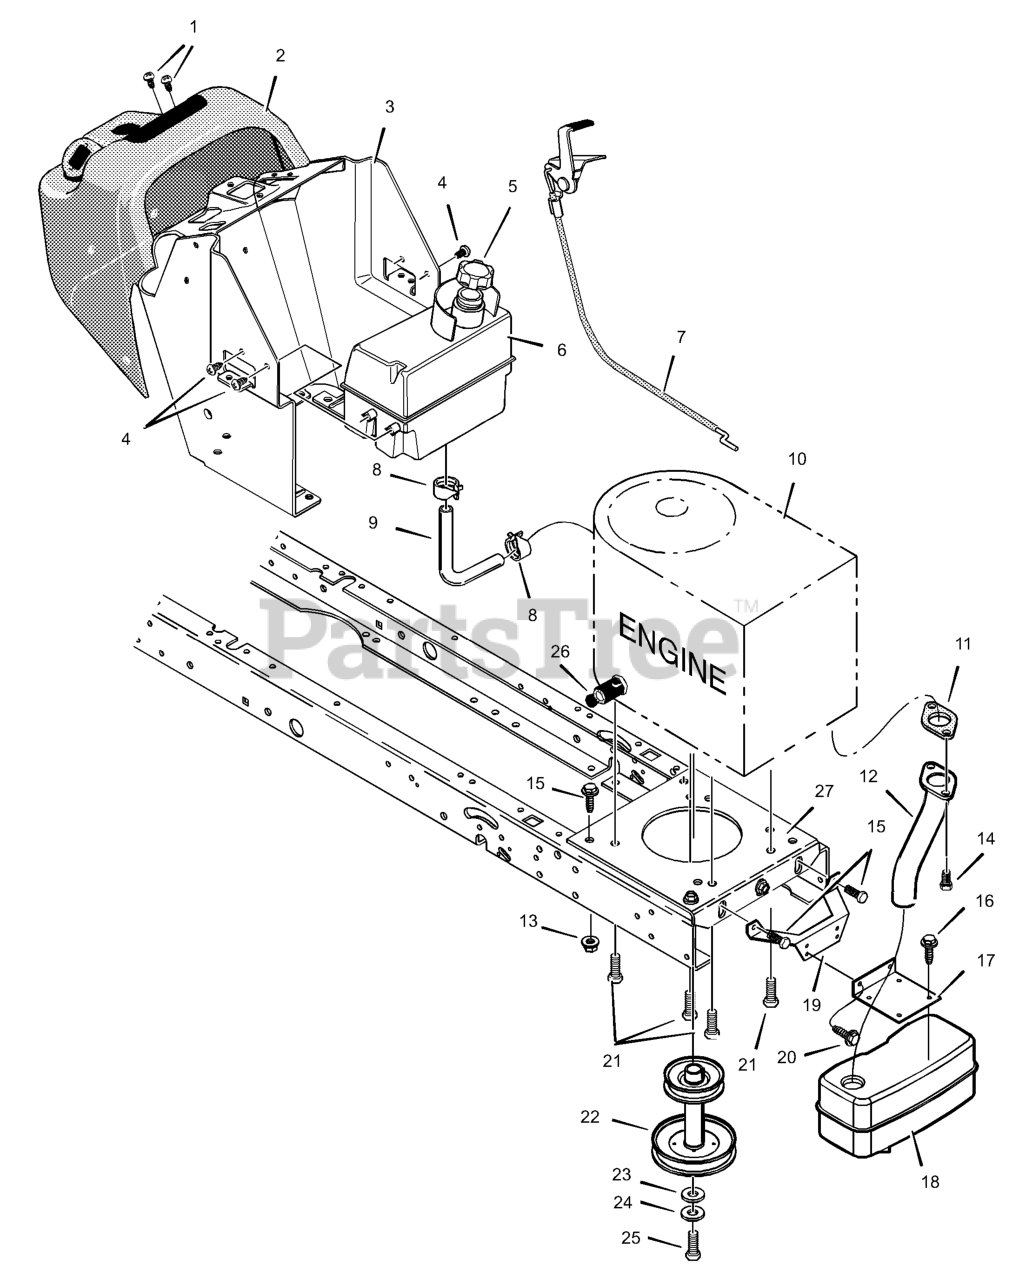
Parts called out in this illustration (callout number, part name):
1	Screw
3	Console
5	Cap, Fuel
6	Tank, Fuel
7	Control, Throttle
8	Clamp, Hose
9	Fuel Line (Must cut to length)
10	Engine *
11	Gasket, Exhaust
12	Tube, Exhaust
13	Nut
17	Bracket, Muffler
18	Muffler
19	Bracket, Muffler Mount
21	Bolt, Engine Mount
22	STACK PULLEY ASSEMBLY
24	Washer, Star
25	Bolt, Hex
26	Drain, Oil
27	Plate, Engine Mount
